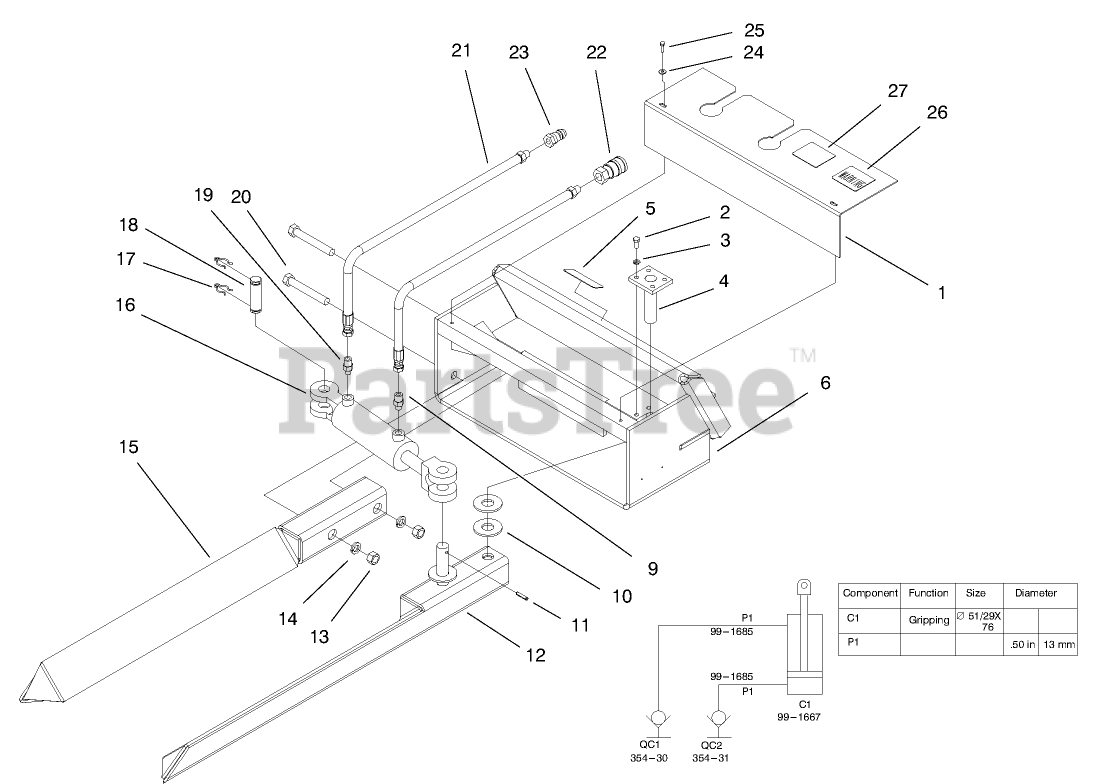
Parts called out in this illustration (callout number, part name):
1	SHIELD ASM
2	SCREW-HSH
3	WASHER-LOCK
6	FRAME
10	WASHER-FLAT
11	PIN-ROLL, SLOTTED
12	ARM-PIVOT, LH
13	NUT-HEX
14	WASHER-LOCK
15	ARM-PIVOT, RH
17	CLIP-PIN
20	SCREW-HH
21	HYD HOSE ASM
22	QUICK COUPLER - FEMALE
23	QUICK COUPLER - MALE
24	WASHER-FLAT
26	DECAL-WARNING
27	DECAL-RATING, LOAD
